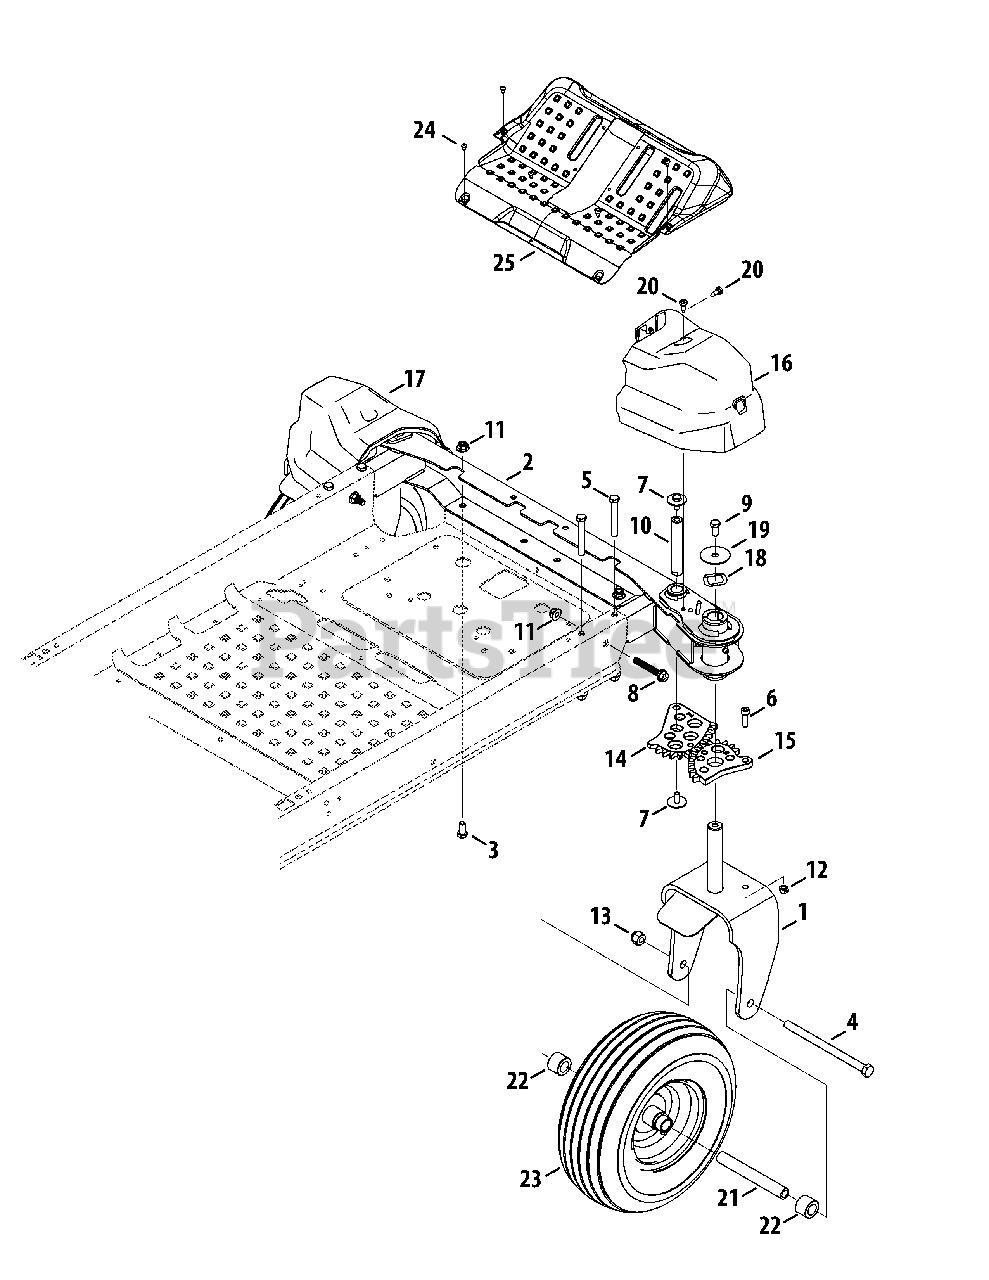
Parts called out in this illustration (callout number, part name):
1	Caster Wheel Bracket
2	Front Axle
3	Hex Cap Screw 3/8-16 x .75
4	Bolt 1/2-20 x 7.25
5	Screw 3/8-16 x 2.75
6	Socket Head Screw 5/16-18 x 1.00
7	Hex Cap Screw 5/16-18 x .75
8	Hex Flange Screw 3/8-16 x 2.00
9	Hex Cap Screw 3/8-16 x .750
10	Pivot Gear Steering Shaft
11	Flange Lock Nut 3/8-16 Gr. 5
12	Hex Lock Nut 5/16-18
13	Hex Lock Nut 1/2-20
14	12-Tooth Variable Gear
15	13-Tooth Variable Spur Gear
16	Axle Cover, RH
17	Axle Cover, LH
18	Wave Washer, 1.25 x 1.00 x .300
19	Shoulder Spacer 1.75 x .180
20	Shoulder Screw 1/4-20
21	Spacer .51 x .75 x 5.825
22	Hub .76 x 1.23 x .92
23	Wheel Assembly 13 x 5 x 6 (Grey)
24	Self-Tapp Screw 1/4-20 x .50
25	Floor Board
26	Hex Flange Screw 3/8-16 x 2.0
